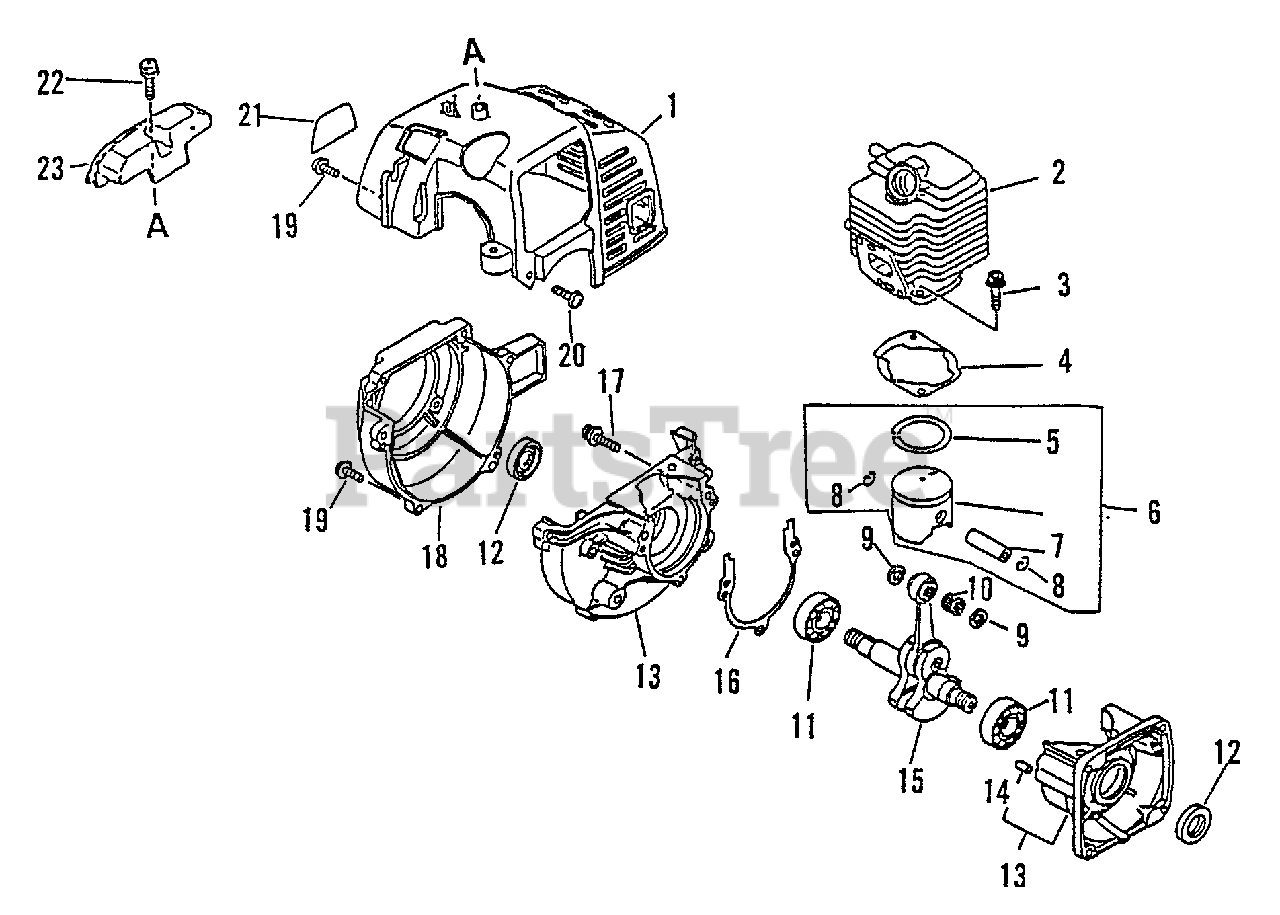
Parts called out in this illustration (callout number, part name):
1	COVER, ENGINE - GRAY
2	CYLINDER
3	BOLT 5×22
4	GASKET, CYLINDER
5	RING, PISTON
6	PISTON KIT
7	PIN, PISTON 8
8	RING, SNAP
9	WASHER, THRUST
10	BEARING, NEEDLE
11	BEARING, BALL - 6201 C3
12	SEAL, OIL 12
13	CRANKCASE KIT
14	PIN, LOCATING 4
15	CRANKSHAFT ASSY
16	GASKET, CRANKCASE
17	SCREW 5×28
18	COVER, FAN - GRAY
19	SCREW 4×16
20	SCREW 4×12
21	LABEL - MODEL 2310
22	SCREW 5×16
23	GUARD, TOP - BLACK
